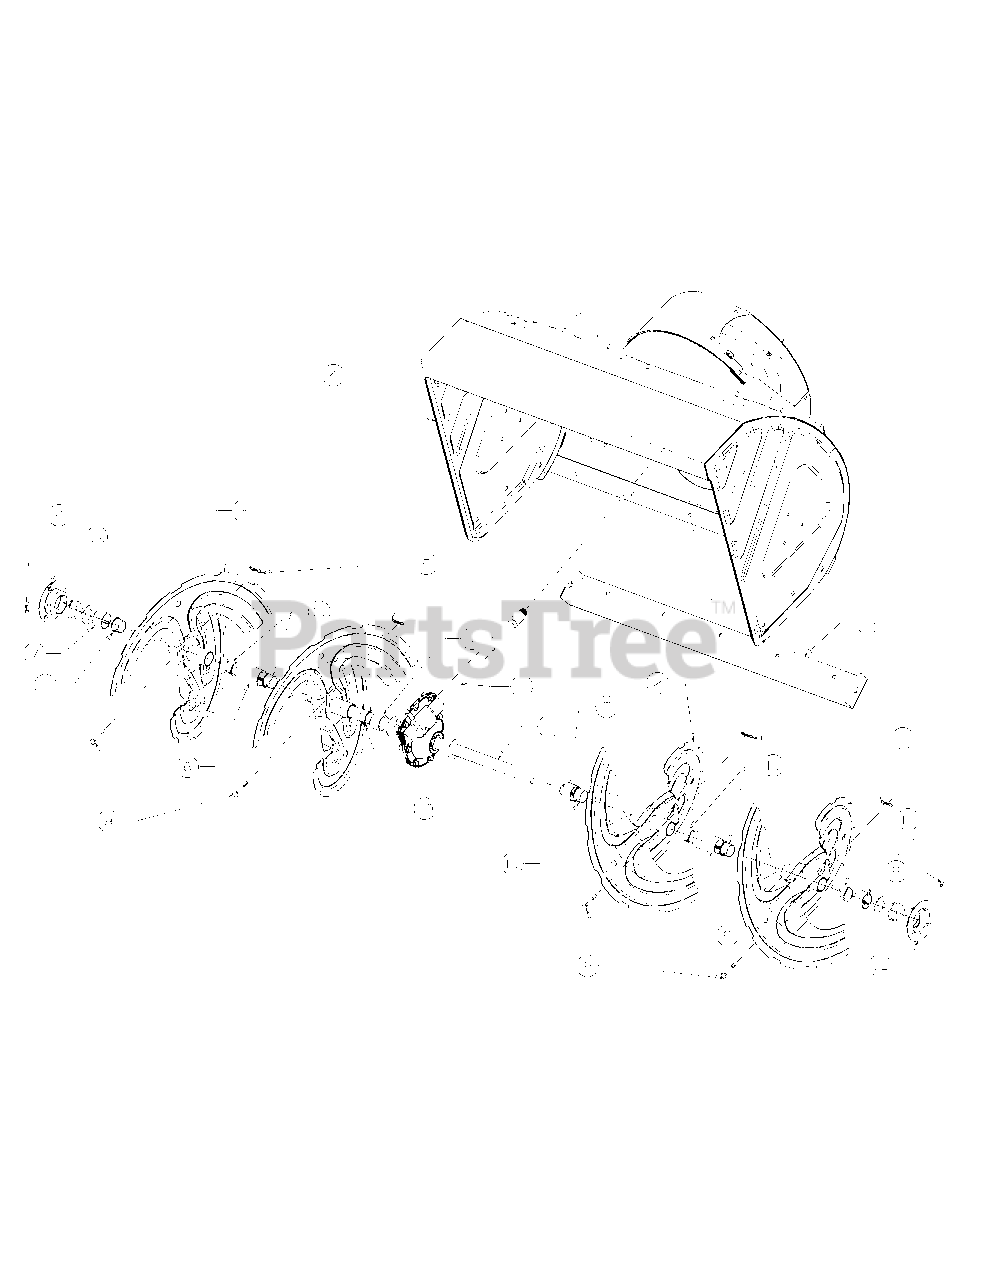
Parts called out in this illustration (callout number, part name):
1	Gear Assy-Auger
2	Spiral Asm:LH 900
3	Spiral Asm:RH 900
4	Housing Assy-Auger
5	Pin-Cotter
6	Spacer: 1.50 Od X
7	Spacer: 1.50 Od X
8	Grease Fitting
9	Wheel:Deck:5.0 Dia B
10	Axle:Sprl:32.12
11	Bushing
12	Housing:Bearing
13	Plate-Shave 33"
